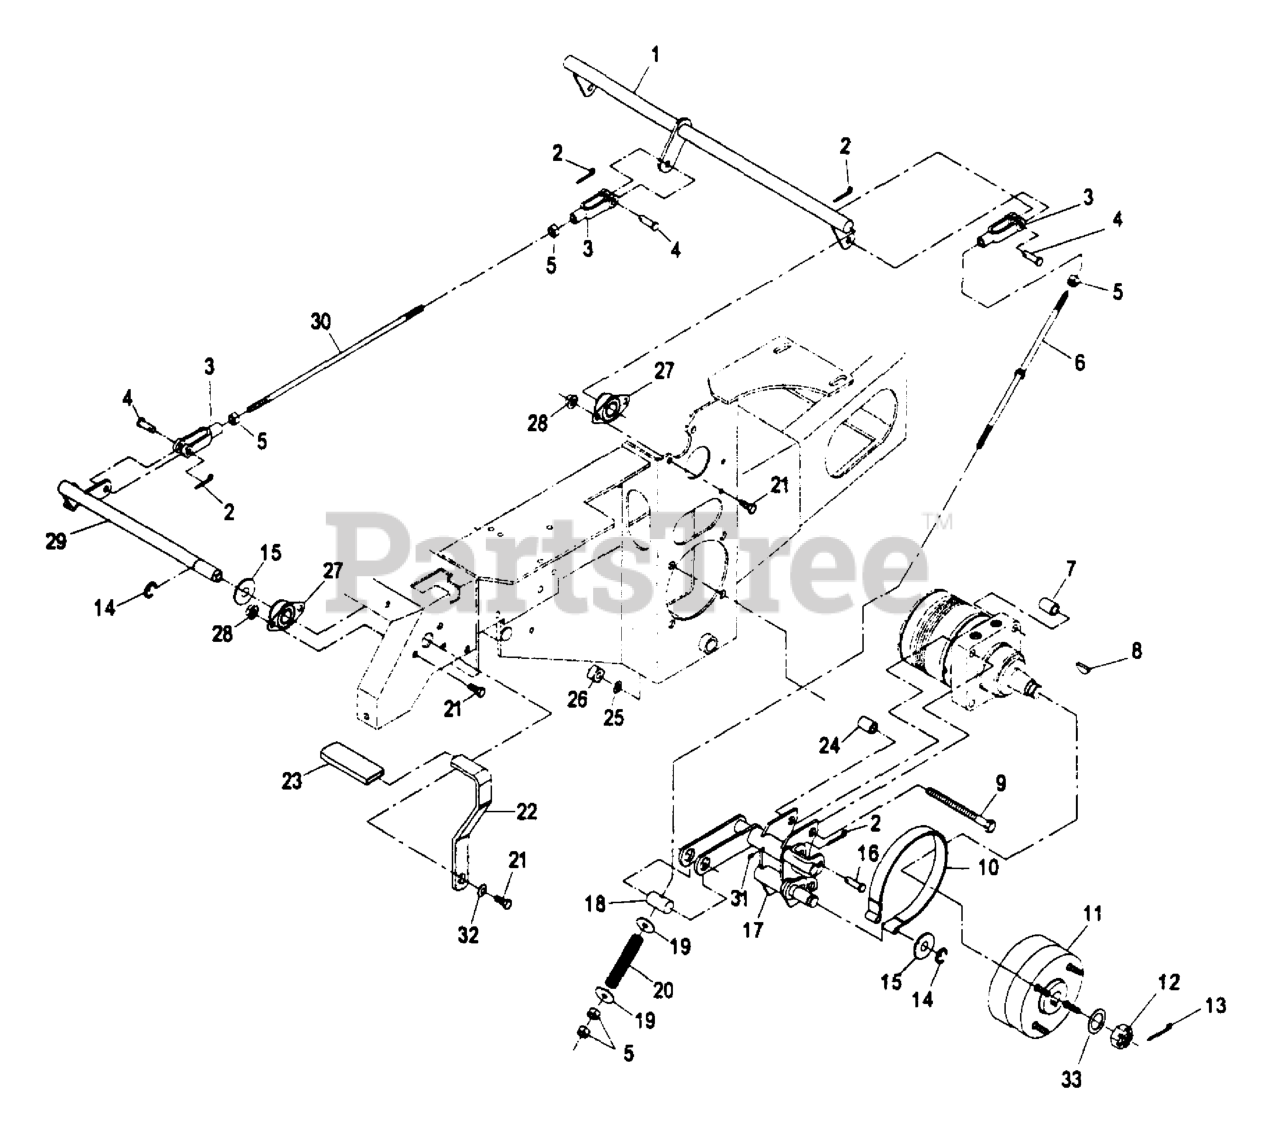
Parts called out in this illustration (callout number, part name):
1	CRANK-BRAKE, PARK
3	YOKE-LINKAGE, BRAKE
4	PIN-CLEVIS
6	ROD-BRAKE
7	SPACER-WHEEL
10	BAND,BRAKE
13	PIN-COTTER
16	PIN,CLEVIS 3/8X2
17	WLD,BRAKE BRACKET LH
18	PIN-TRUNION
20	SPRING-BRAKE
22	HANDLE-BRAKE, PARK
23	GRIP-LEVER
24	SPACER-WHEEL
27	BEARING-FLANGE, SIDE
30	LINKAGE-HANDLE, BRAKE
31	1481
33	WASHER-SPACER
